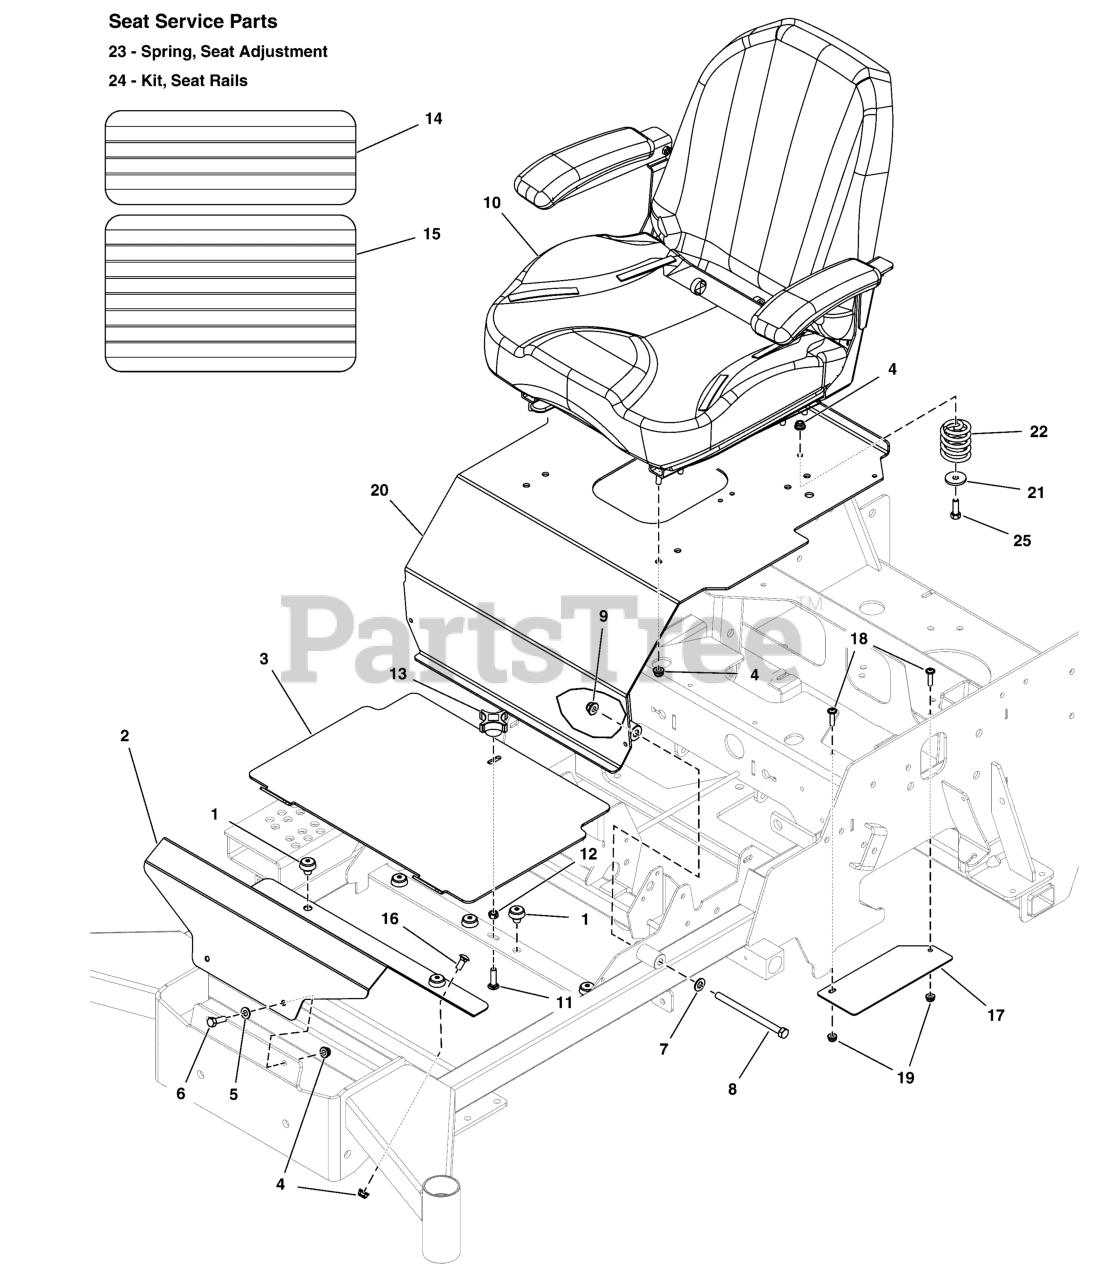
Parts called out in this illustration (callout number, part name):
1	MNT, VBRTN, RBBR
2	PLATE, FLOOR RIGID, S125XT - RED
3	PLATE, FLOOR, REMOVABLE, S125XT - RED
4	NUT, 5/16-18 HEX NYLOCK FLANGE NUT
5	WASHER, 5/16" SAE
6	BOLT, 5/16-18 X 1" GRD5 YZ
7	WASHER, 3/8 SAE
8	BOLT, 3/8-16 X 5-1/2" GD5 CZ
9	NUT, 3/8 - 16 HEX NYLOCK FLANGE
10	SEAT, 907, W/ARM REST, W/SWITCH, NO BEAD
11	BOLT, 5/16-18 X 1-1/4, CARRIAGE, GD5, CZ
12	NUT, 5/16-1/8, HEX, CNTR LK, ZINC PHOS/OIL
13	KNOB-INT THR .312-18 4-ARM 2.12WD 1.06LG
14	SAFETY WALK, FLOOR REST, 16.00 X 6.00
15	SAFETY WALK, FLOOR PLATE, S50X, 10X17.13
16	BOLT, 5/16-18 X 3/4, CARRIAGE, GD5, CZ
17	PLATE, SEAT BELT GUARD - S125XT - BLK
18	SCREW, FLANGE, ALLEN HD, 1/4-20 X .75 SS
19	NUT, 1/4-20 Hex Nylock Flange
20	ASSM, SEAT PLATE W/DECALS, S125XT (2019)
21	WASHER, .34 X 1.25 X 10 GA
22	SPRING, SEAT SUPPORT
23	SPRING, EXTENSION, SEAT ADJUSTMENT (BLK OR SLVR)
24	KIT, SEAT RAILS (COMPLETE)(SV)
25	BOLT, 5/16-18 X 3/4 GD5
